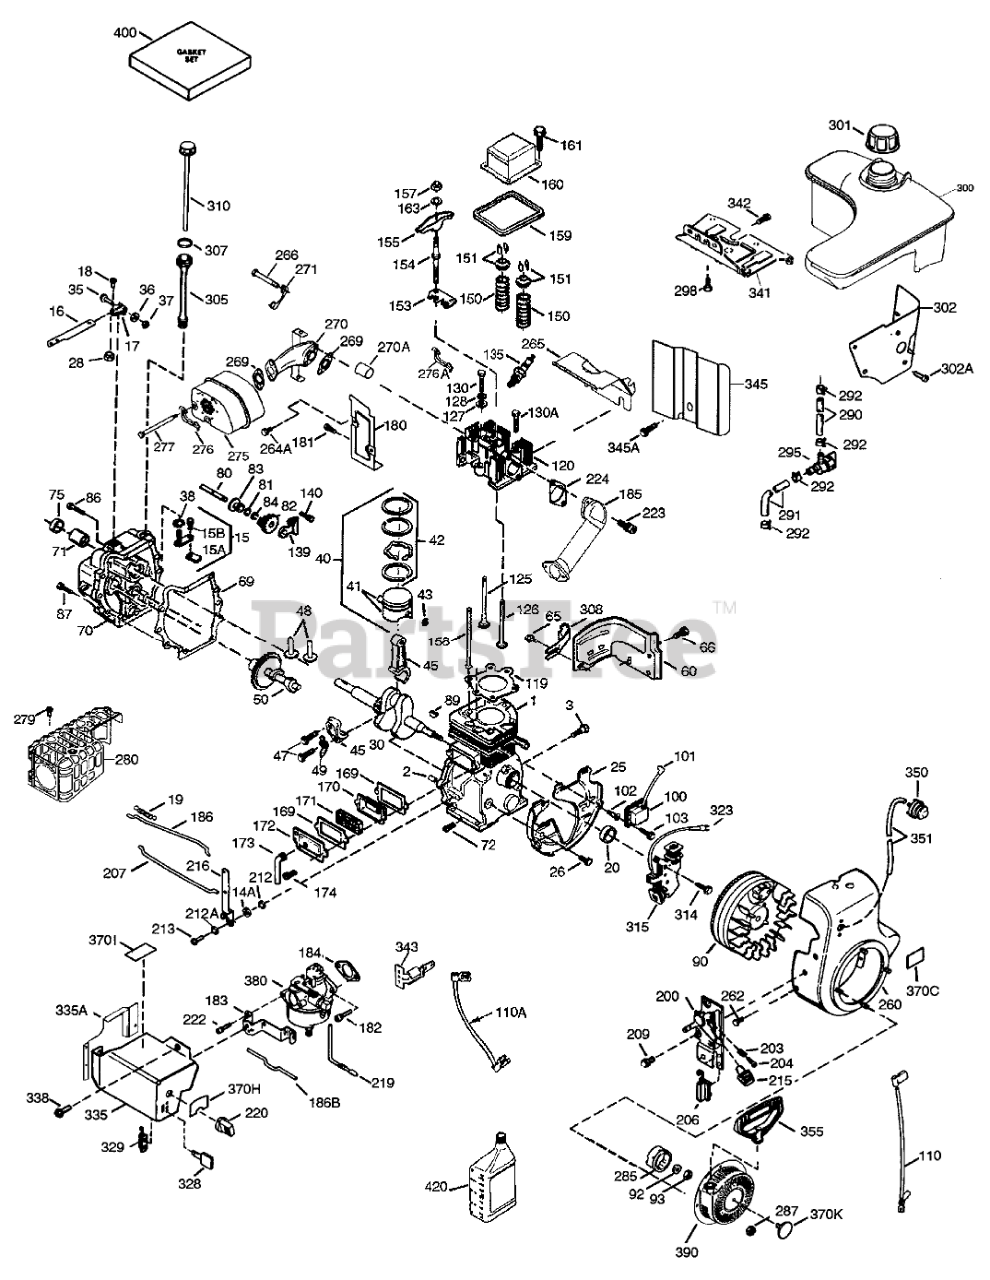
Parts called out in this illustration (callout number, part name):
1	Cylinder Asm (Incl. Ref. #2, 20, & 72)
2	Pin-Dowel
3	Screw (1/4-20x1/2)
14A	Washer
15	Governor (Incl. Ref. #15A & 15B)
15A	Yoke-Governor
15B	Screw (6-40x5/16)
16	Governor Lever
17	Clamp-Lever, Governor
18	Screw (T-15, 8-32x7/16)
19	Spring-Extension
20	Seal-Oil
25	Baffle-Housing, Blower
26	Screw (1/4-20x19/32)
28	Nut-Lock
30	Crankshaft
35	Screw
36	Washer-Lock
37	Nut-Lock
38	Ring-Retaining
40	Piston-Pin and Ring Set (STD)
40	Piston- Pin and Ring Set (.010 O S)
41	Piston & Pin Asm (Std.)(Incl. Ref. #43)
41	Piston & Pin Asm (.010" OS)(Incl. Ref. #43)
42	Ring Set (STD)
42	Ring Set (.010 O S)
43	Ring-Retaining, Piston Pin
45	Connecting Rod Asm (Incl. Ref. #47, & 49)
47	Bolt-Rod, Connecting
48	Lifter-Valve
49	Dipper-Oil
50	Camshaft
60	Extension-Housing, Blower
65	Screw (10-24 x 9/16)
66	Screw
69	Gasket-Cover, Cylinder
70	Cylinder Cover (Incl. Ref. #71, 75, & 80)
71	Bushing-Crankshaft
72	Plug-Drain, Oil (SQH 1/4-18)
75	Seal-Oil
80	Shaft-Governor
81	Washer-Flat
82	Governor Gear ASM
83	Spool-Governor
84	Ring-Retaining
86	Screw (1/4-20x1-3/16)
87	Screw (1/4-20x1-11/16)
89	Key-Flywheel
90	Flywheel ASM
92	Washer-Belleville
93	Nut-Flywheel
100	Solid State ASM
101	Cover-Spark Plug
102	Stud-Mounting, Solid State
103	Screw (T-15, 10-24 x 15/16)
110	Wire-Ground
110A	Wire-Ground
119	Gasket-Head, Cylinder
120	Cylinder Head
125	Valve-Exhaust (STD)
125	Valve-Exhaust (1/32)
126	Valve-Intake (STD)
126	Intake Valve (1/32)
127	Washer-Flat
128	Washer-Belleville
130	Screw (5/16-18x1-1/2)
131A	Screw (T-30, 1/4-20x15/32)
135	Spark Plug-Resistor (R N 4C)
139	Bracket-Gear, Governor
140	Screw (10-24x1/2)
150	Spring-Valve
151	Keeper-Spring, Valve
153	Guide-Rod, Push
154	Stud-Arm, Rocker
155	Arm-Rocker
157	Nut-Jam
158	Rod-Push
159	Gasket-Cover, Rocker Arm
160	Cover-Arm, Rocker
161	Screw
163	Washer
169	Gasket-Cover, Valve
170	Body-Breather
171	Element-Breather
172	Cover-Valve
173	Tube-Breather
174	Screw
180	Extension-Housing, Blower
181	Screw (10-24 x 9/16)
182	Screw (T-30, 1/4-20 X 27-32)
183	Bracket-Choke
184	Gasket-Carburetor To Intake Pipe
185	Pipe-Intake
186	Link-Governor
186B	Spring-Choke
200	Control Bracket (Incl. Ref.#203 204 & 206)
203	Spring-Compression
204	Screw (T-10, 5-40x7/16)
206	Terminal
207	Link-Throttle
209	Screw (10-32 x 1/2)
209A	Screw (10-24 X 29/32)
212	Bushing
212A	Bushing
215	Knob-Control
217	Lever-Bellcrank
219	Rod-Choke
220	Knob-Control
222	Screw (10-32 x 1/2)
223	Screw (T-30, 5/16-18 X 7/8)
224	Gasket-Pipe
260	Housing-Blower
262	Screw
264A	Screw (1/4-20 X 5/8)
265	Cover-Head, Cylinder
266	Screw (5/16-18 X 1-9/32)
269	Gasket-Manifold, Exhaust
270	Manifold, Exhaust
270A	Liner-Port, Exhaust
271	Plate-Locking
275	Muffler
276	Plate-Locking
276A	Plate-Locking
277	Screw (5/16-18 X 4-1/2)
281	Screw
282	Screw (8-32 x 3/8)
285	Cup-Starter
287	Nut and Lock Washer (1/4-28)
290	Line-Fuel
291	Line-Fuel (8.62)
292	Clamp-Line, Fuel
295	Valve-Shut Off, Fuel
298	Screw (1/4-15x7/8)
300	Fuel Tank (Incl. Ref. #292 & 301)
301	Cap-Fuel
302	Extension-Tank, Fuel
302A	Screw (10-32 x 1/2)
305	Tube-Fill, Oil
307	O-Ring
308	Clip-Tube, Fill
310	Dipstick
314	Screw (1/4-20 x 3/4)
315	Alternator Coil (18 Watt)(Incl. Ref. #323)
323	Terminal
328	Key-Ignition
329	Terminal
335	Spring
335A	Cover-Carburetor
338	Screw (10-32 x 1/2)
341	Bracket-Tank, Fuel (Black)
342	Screw (1/4-20x19/32)
345	Baffle-Heat
345A	Screw (10-32 x 1/2)
350	Primer ASM
351	Line-Primer
355	Handle-Starter, Mitten Grip
370C	Decal-Primer, International Symbol
370H	Decal-Choke
370I	Decal-Warning (Bilingual)
370K	Decal-Tecumseh Logo for Top of Recoil Starter
380	Carburetor (Incl. Ref. #184)
390	Starter-Rewind
396	Starter-Electric (110 Volt)
400	Gasket Set
420	Oil-Engine (SAE 5W30)
